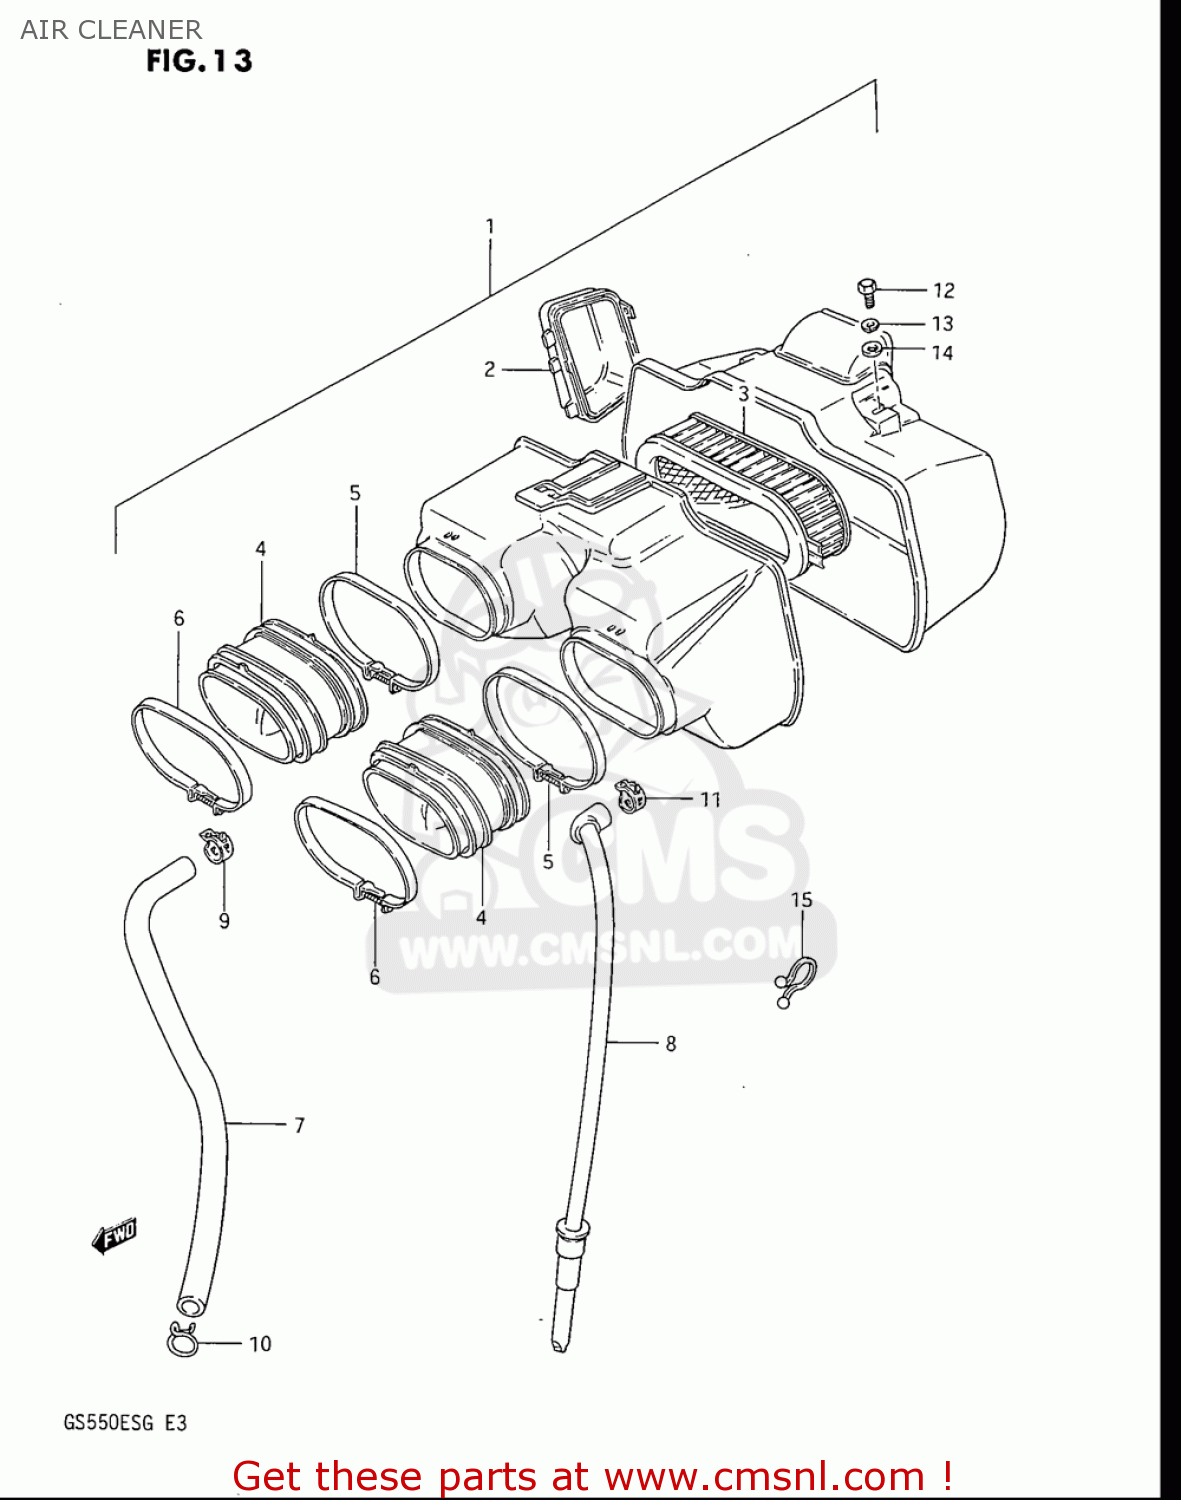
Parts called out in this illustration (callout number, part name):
2	CAP,AIR CLEANER
3	FILTER,AIR CLEANER
4	TUBE,AIR CLEANER OUTLET
5	CLAMP,AIR CLEANER
6	CLAMP,CARBURETOR SIDE
8	TUBE,DRAIN
9	CLIP
10	CLIP
11	CLIP
12	BOLT
13	WASHER,LOCK
14	WASHER
